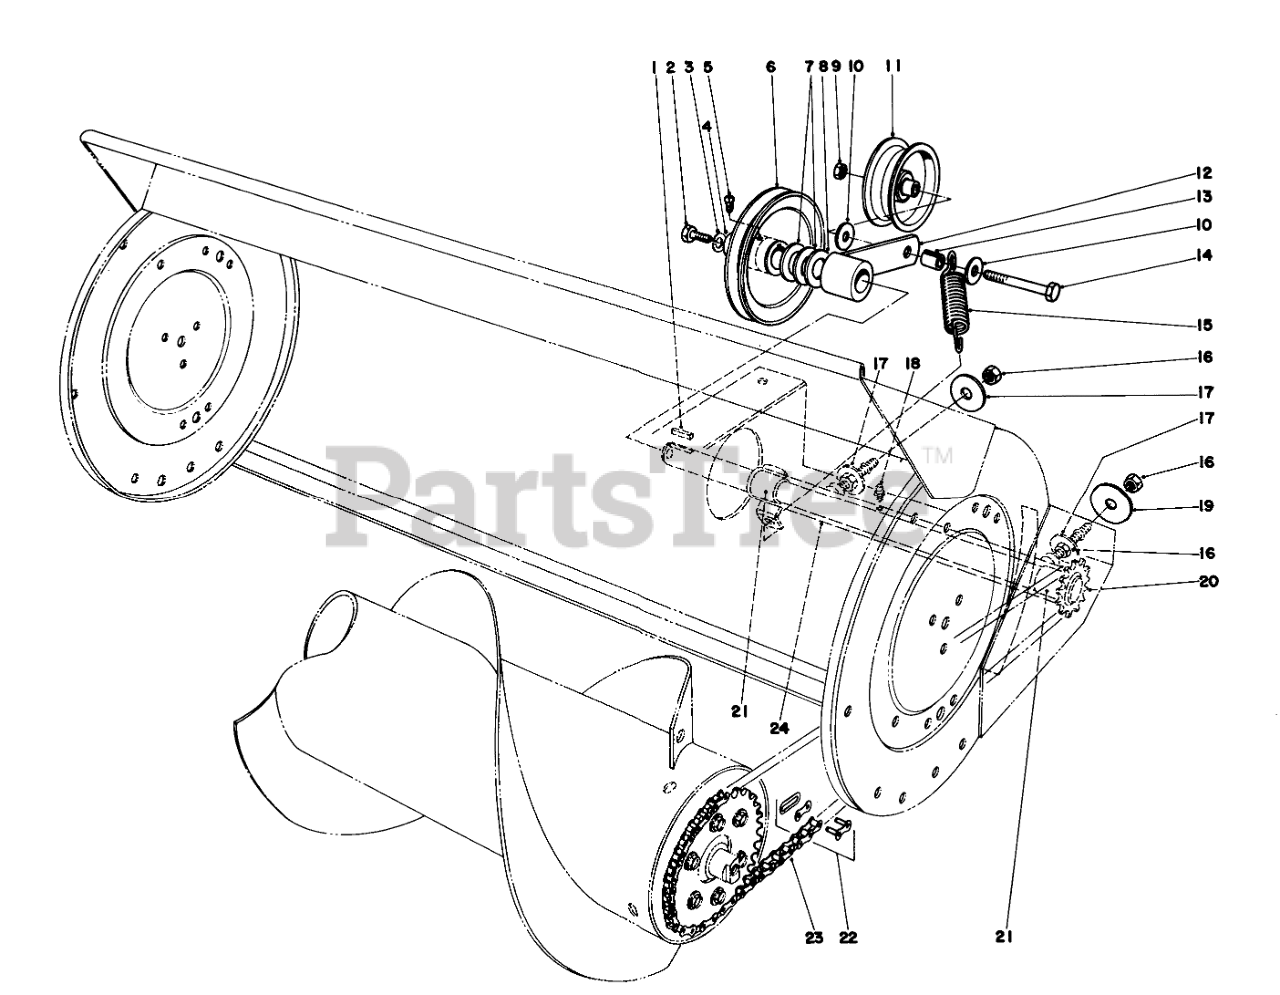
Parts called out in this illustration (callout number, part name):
1	KEY-SQUARE
2	SCREW-HH
3	WASHER-LOCK
4	WASHER-FLAT
5	SCREW-SQH
6	Pulley
7	Washer
8	Washer
9	NUT-LOCK, CONE
10	WASHER-FLAT
11	IDLER PULLEY ASM
12	Idler Arm
13	Spacer
14	SCREW-HH
15	Spring
16	NUT-HH
17	WASHER-FLAT
18	FITTING-GREASE
19	Flat Washer
20	SHAFT/SPROCKET ASM
21	Bushing-Jackshaft
22	LINK-CONNECTING
23	Roller Chain
24	Jackshaft Housing (Incl. Ref. #18)
